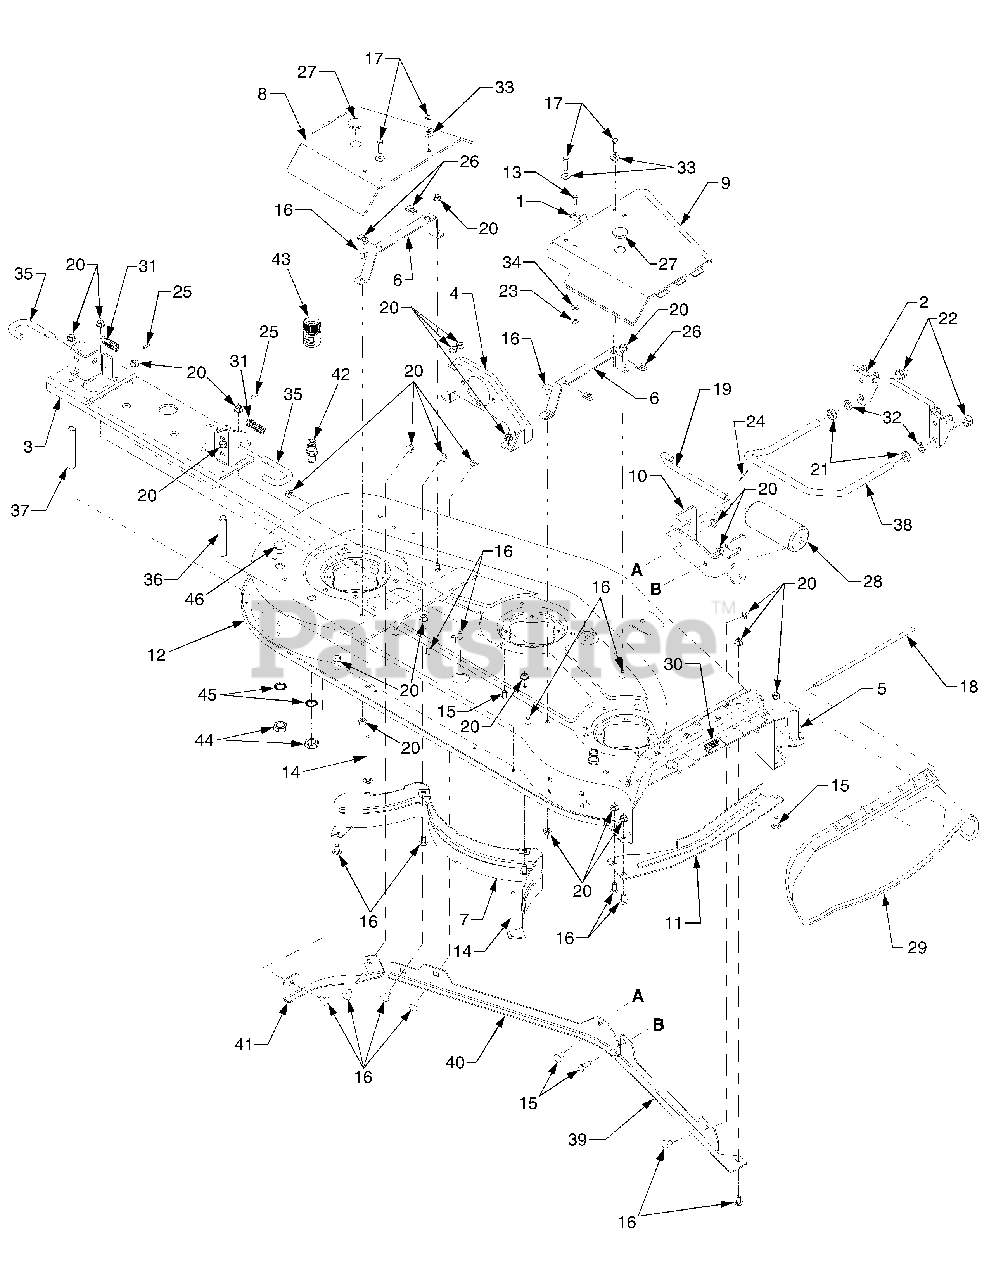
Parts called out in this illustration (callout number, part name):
1	Bracket, Hook Retainer
2	Bracket, Front Lift
3	Bracket, Gearbox
4	Bracket, Drive
5	Bracket, Chute Stop
7	Baffle, Rear Inner
8	Cover, Belt (L.H.)
9	Cover, Belt (R.H.)
10	Bracket, Roller Front
11	Guard, Finger
12	Deck Assembly (w/o Deck wash holes)
12	Housing, Deck (w/ Deck wash holes)
12	Label, 54"
12	Label, Danger
12	Label, Danger L.H. Side
13	Screw, Hex Cap 1/4-20 x .62 GR5
14	Carriage, Bolt 3/8-16 x 5.0 GR5
15	Carriage, Bolt 3/8-16 x 1.0
16	Carriage, Bolt 3/8-16 x .75
17	Screw, HHC, 5/16-18 x 1.0 GR5 Replaces 710-3232 Thmb Scrw
18	Pin, Hinged .375 x 14.06
19	Pin, Roller 1/2 x 7.31
20	Nut, Flange Lock 3/8-16
21	Nut, Hex Jam 5/8-11
22	Nut, Hex Lock 5/8-11
23	Nut, Hex Flange Lock 1/4-20
24	Pin, Cotter 3/32 x 1.25
25	Pin, Spirol
26	Nut, “U" 5/16-18
27	Plug, Button
28	Roller, Front
29	Deflector, Chute
29	Label, Danger
30	Spring, Torsion
31	Spring, Compression
32	Washer, Lock 5/8" I.D.
33	Washer, Bell .34" I.D.
34	Washer, Bell .265 x .75 x .062
35	Pin, Mower Support
36	Spacer, .405" I.D. x 3.875" Lg.
37	Spacer, .405" I.D. x 4.075" Lg.
38	Rod, Front Lift
42	Nozzle, Deck Wash - Mfg. Code 1J014G and after
43	Adapter, Nozzle - Mfg. Code 1J014G and after
44	Nut, Hex, M16-1.5 - Mfg. Code 1J014G and after
45	Washer, Lock - Mfg. Code 1J014G and after
46	Plug, Screw, M16-1.5 - Mfg. Code 1J014G and after
